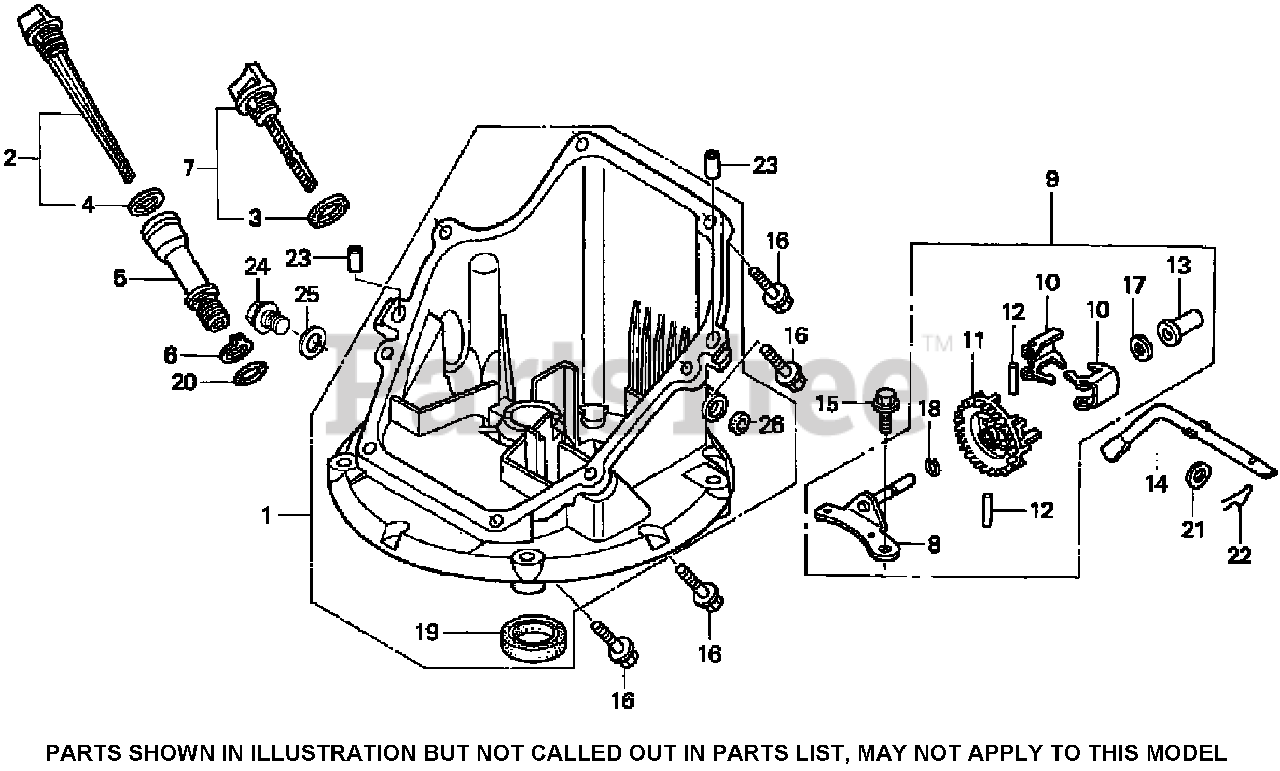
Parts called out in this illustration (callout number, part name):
1	PAN ASM., OIL
2	DIPSTICK-OIL
4	GASKET-CAP, OIL FILLER
5	EXTENSION-FILLER, OIL
6	WASHER-LOCK, EXTENSION
8	SHAFT-HOLDER, GOVERNOR
9	GOVERNOR ASM
10	WEIGHT-GOVERNOR
11	HOLDER-WEIGHT, GOVERNOR
12	PIN-WEIGHT, GOVERNOR
13	SLIDER-GOVERNOR
14	SHAFT-ARM, GOVERNOR
15	BOLT-FLANGE (6X14)
16	BOLT-FLANGE (6X25)
17	WASHER-THRUST (6MM)
18	CLIP-HOLDER, GOVERNOR
19	SEAL-OIL (28X41.25X6)
20	O-RING
21	WASHER-PLAIN (6MM)
22	PIN-LOCK (8MM)
23	PIN-DOWEL (8X20)
